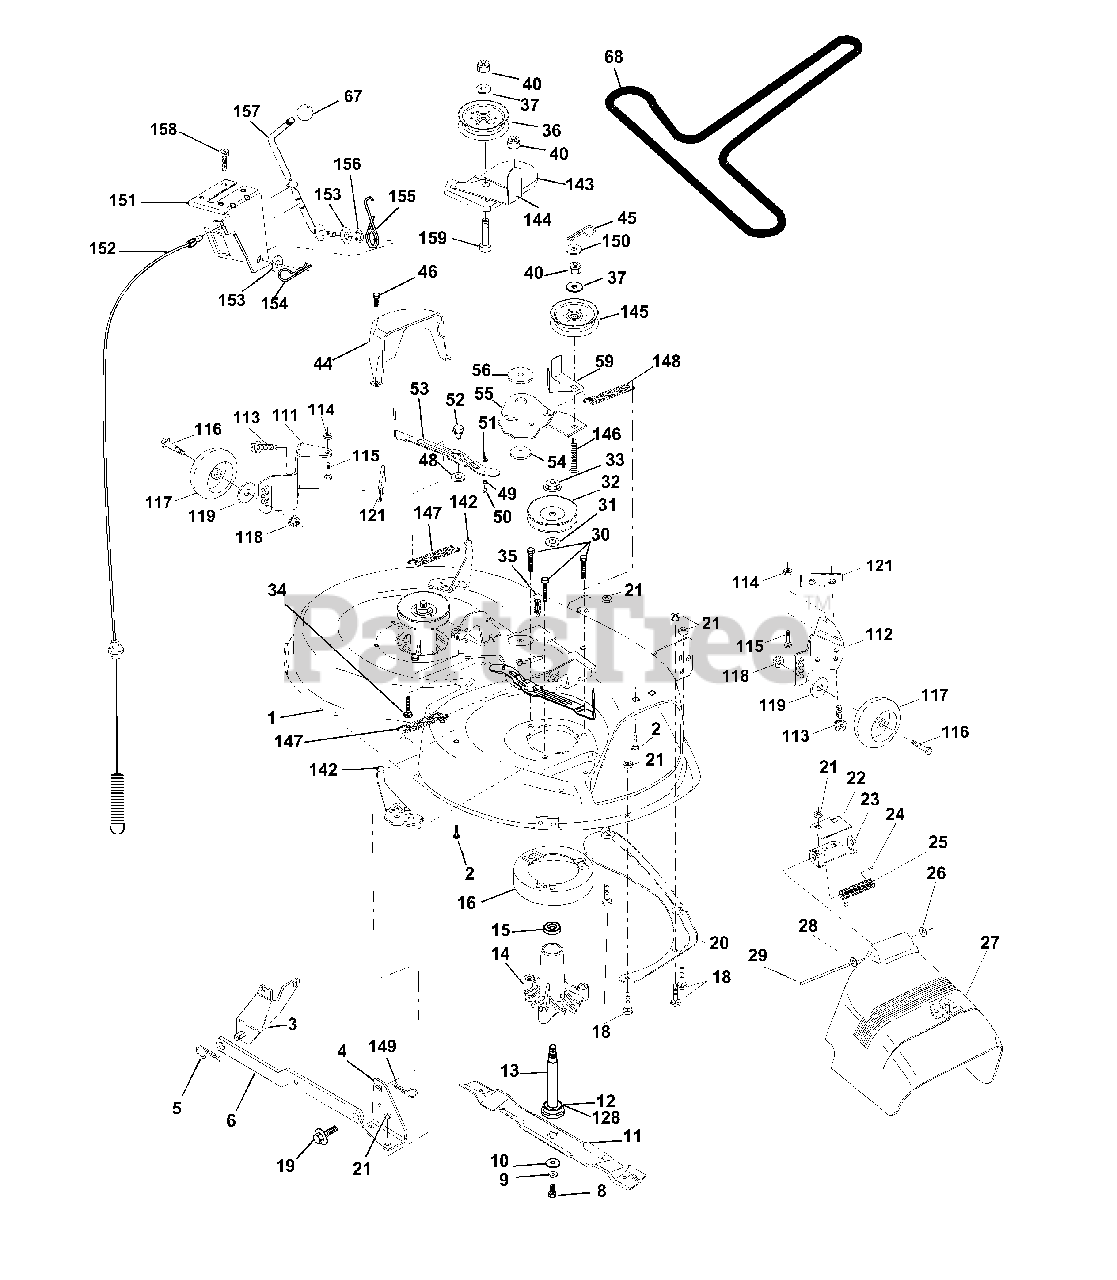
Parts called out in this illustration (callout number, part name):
1	Mower Deck Assembly, 42"
2	Bolt
3	Bracket Asm Fr. Sway Bar 3/42
4	Bracket Asm Deck 42" Sway Bar
5	Retainer Spring
6	Arm, Suspension, Rear
8	Bolt 3/8-24 x 25 Grade 8 patched
9	Washer, Lock
10	Washer,Hardened
11	Blade
12	Bearing, Ball #6204
13	Shaft Assembly, Mandrel, Vented
14	Housing, Mandrel, Vented
15	Bearing, Ball, Mandrel
16	Stripper, Vented Mower Deck
18	Bolt, Carriage 5/16-18 x 5/8
19	Bolt, Shoulder
20	Baffle, Vortex
21	Nut
22	Stiffener Bracket
23	Bracket, Deflector Mower 42"
24	Cap, Sleeve 80 x 112 Blk Mower
25	Spring, Torsion, Deflector 2 52
26	Nut, Push Phos & Oil
27	Shield, Deflector 42" Blk
28	Washer 11/32 x 5/8 x 16 Gauge
29	Rod, Hinge 42" 6 75 W/G
30	Screw Thdrol Washer Head
31	Washer, Spacer Mower Vented
32	Pulley, Mandrel
33	Nut, Toplock 9/16
34	Bolt
35	Fastener, Christmas Tree
36	Pulley, Idler, Flat
37	Washer 13/32 x 13/16 x 16 Gauge
40	Nut
44	Guard, Mandrel, LH
45	Retainer
46	Screw, Thdrol 1/4-20 x 5/8 T
48	Washer,Hardened
49	Roller Assembly, Cam Follower
50	Bolt, Shoulder #10-24 Grade 5
51	Locknut
52	Bolt, Shoulder 5/16-18 UNC
53	Arm Assembly, Pad, Brake
54	Washer,Hardened
55	Arm, Idler
56	Spacer, Retainer
59	Guard TUV Idler
67	Knob
68	V-Belt, 42" Mower
111	Bracket, Gauge, Wheel LH
112	Bracket, Gauge, Wheel RH
113	Screw 5/16 - 18 x 3/4
114	Nut, Keps 5/16 - 18 UNC
115	Bolt, Carriage 5/16-18 x 1/2
116	Bolt, Shoulder
117	Wheel, Gauge
118	Nut Centerlock 3/8-16
119	Washer 3/8 x 7/8 x 14 Ga.
120	Washer 17/32 x 15/16 x 12 Ga.
121	Bracket, Extruded
128	Washer, Felt
142	Arm Spring Brake Mower
143	Bracket Arm Idler 42"
144	Keeper Belt 42" Clutch Cable
145	Pulley Idler Flat
146	Bolt Carriage Idler
147	Spring Extension
148	Spring Return Idler
149	Retainer Spring Yellow
150	Washer 9/32 x 3/4 x 16 Ga.
151	Bracket Clutch Cable
152	Clutch Cable 42"
153	Washer Flat 3/8" Type B
154	Spring Retainer
155	Spring Retention LVR CLTCH CAB
156	Spacer Clutch Cable
157	Rod Clutch Cable 3/8"
158	Screw Hex Thd Cut 1/4-20 x 5/8
159	Bolt Rdhd Sqn 3/8-16 UNC x 1-3/4
